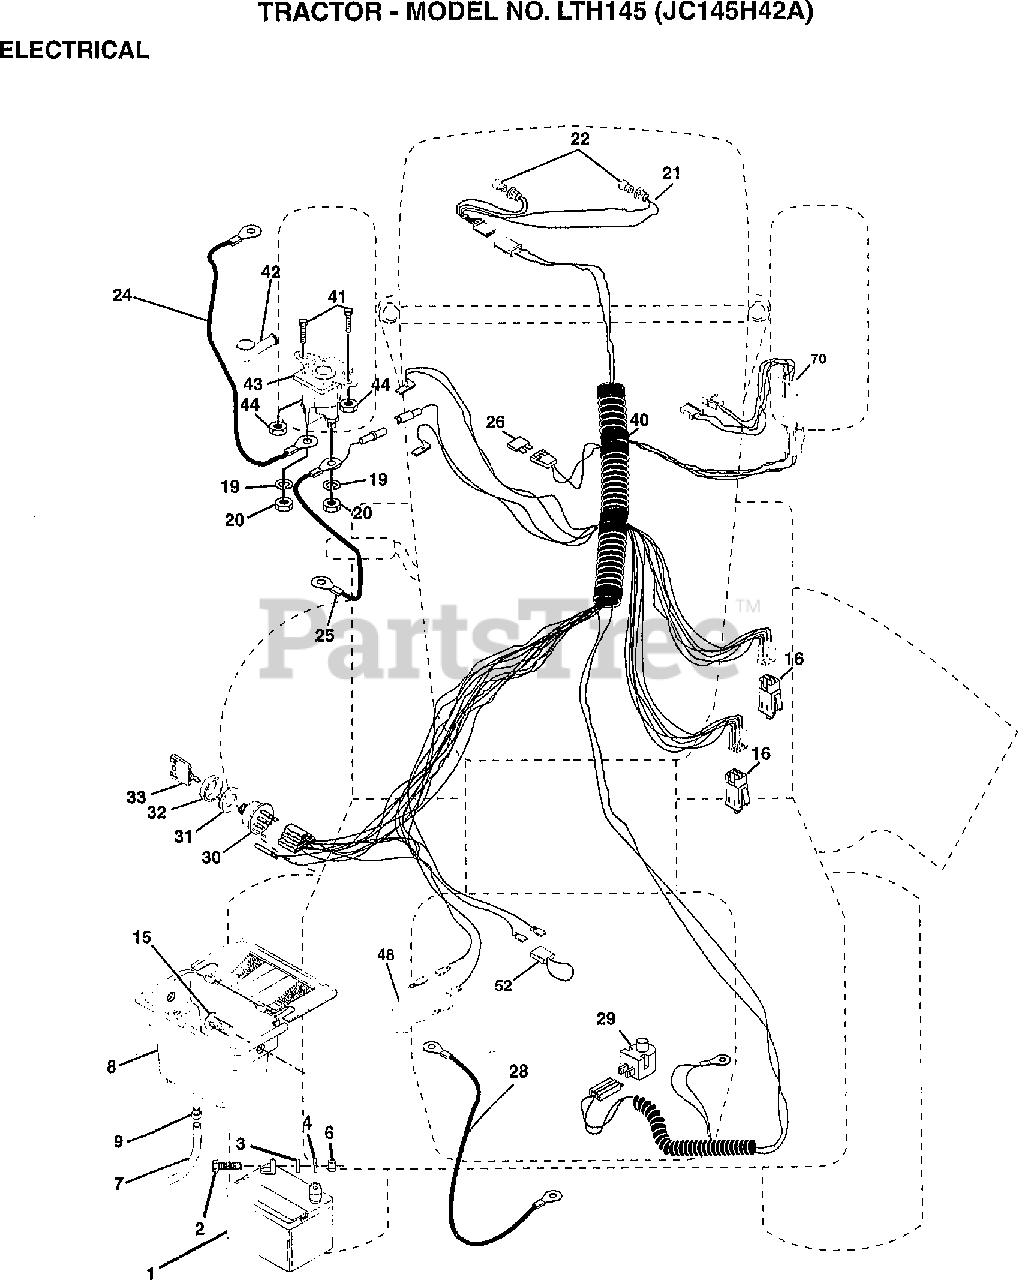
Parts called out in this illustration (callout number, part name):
2	BOLT HEX HD 1/4-20 X 3/4
3	WASHER 9/32 X 5/8 X 16 GA.
4	WASHER, LOCK 1/4
6	NUT, HEX 1/4-20
19	WASHER LOCK 1/4
20	NUT JAM HEX 1/4-20 UNC
41	BOLT BLK FIN HEX 1/4-20 X 1/2
44	NUT KEPS HEX 1/4-20 UNC
